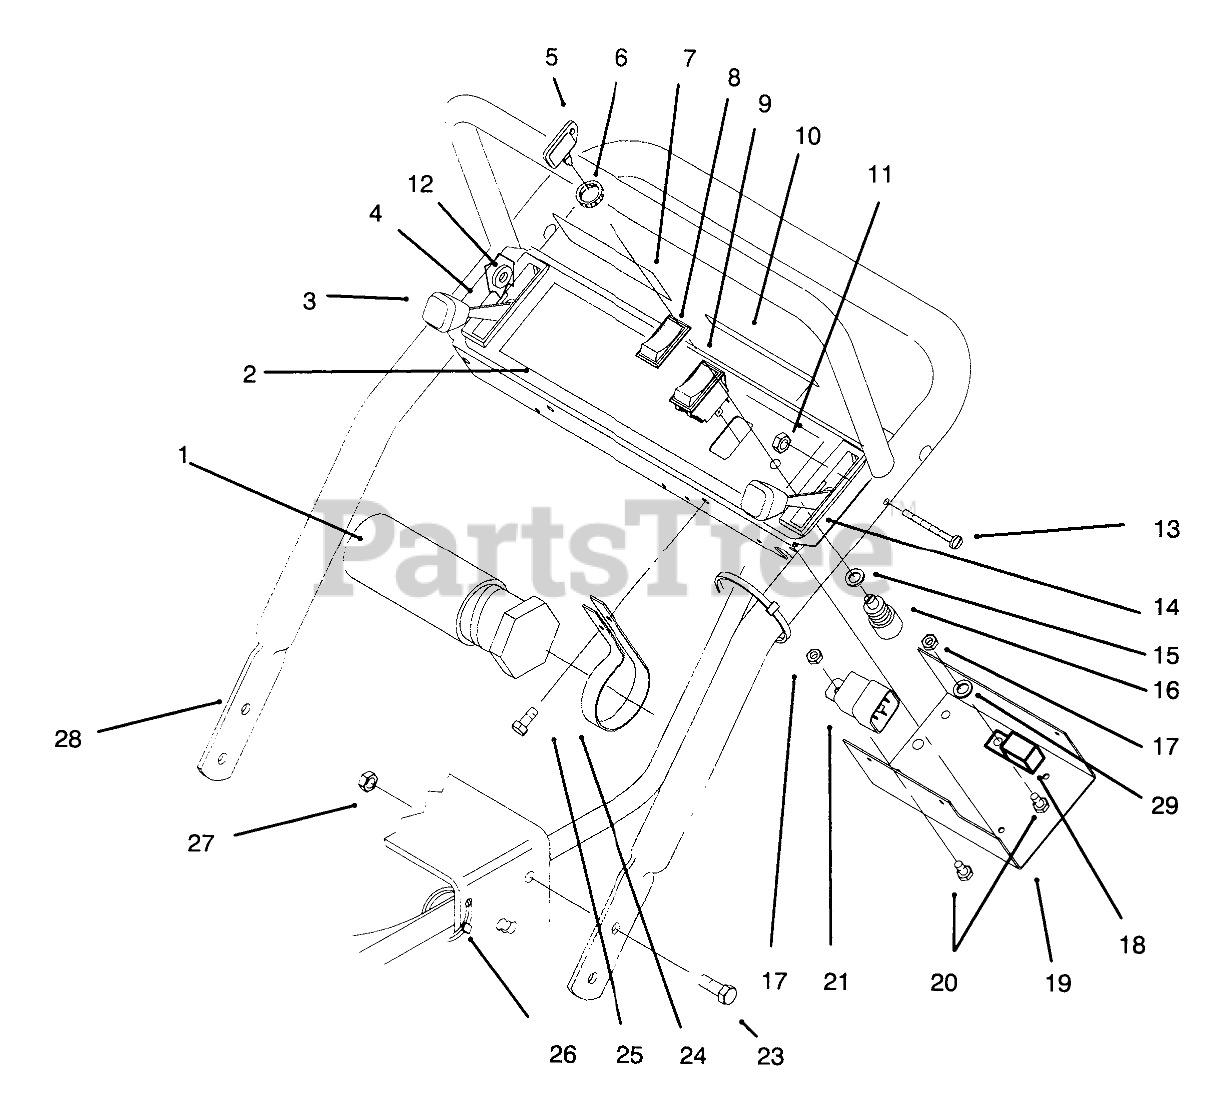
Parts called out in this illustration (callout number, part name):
1	TUBE-MANUAL
2	DECAL - CONTROL PANEL
3	CHOKE CONTROL
4	Panel-Control
5	KEY-IGNITION
6	NUT-HH
7	DECAL-INSTRUCTION
8	BOOT-SWITCH
9	Switch-Clutch (Incl. Ref.#8)
10	DECAL-DANGER
11	NUT-LOCK, NI
12	SPACER
13	SCREW-SHH
14	CONTROL - THROTTLE
15	WASHER-TOOTH, INTERNAL
16	Switch-Ignition(Incl. Ref. #5,6,15)
17	NUT-LOCK, NI
18	Module
19	Panel-Bottom
20	SCREW-HH
21	RELAY
23	SCREW-HHF
24	CLAMP-R
25	SCREW-SHWH
26	TIE-CABLE
27	NUT-HF
28	Handle-Upper
29	WASHER-LOCK/EXT
